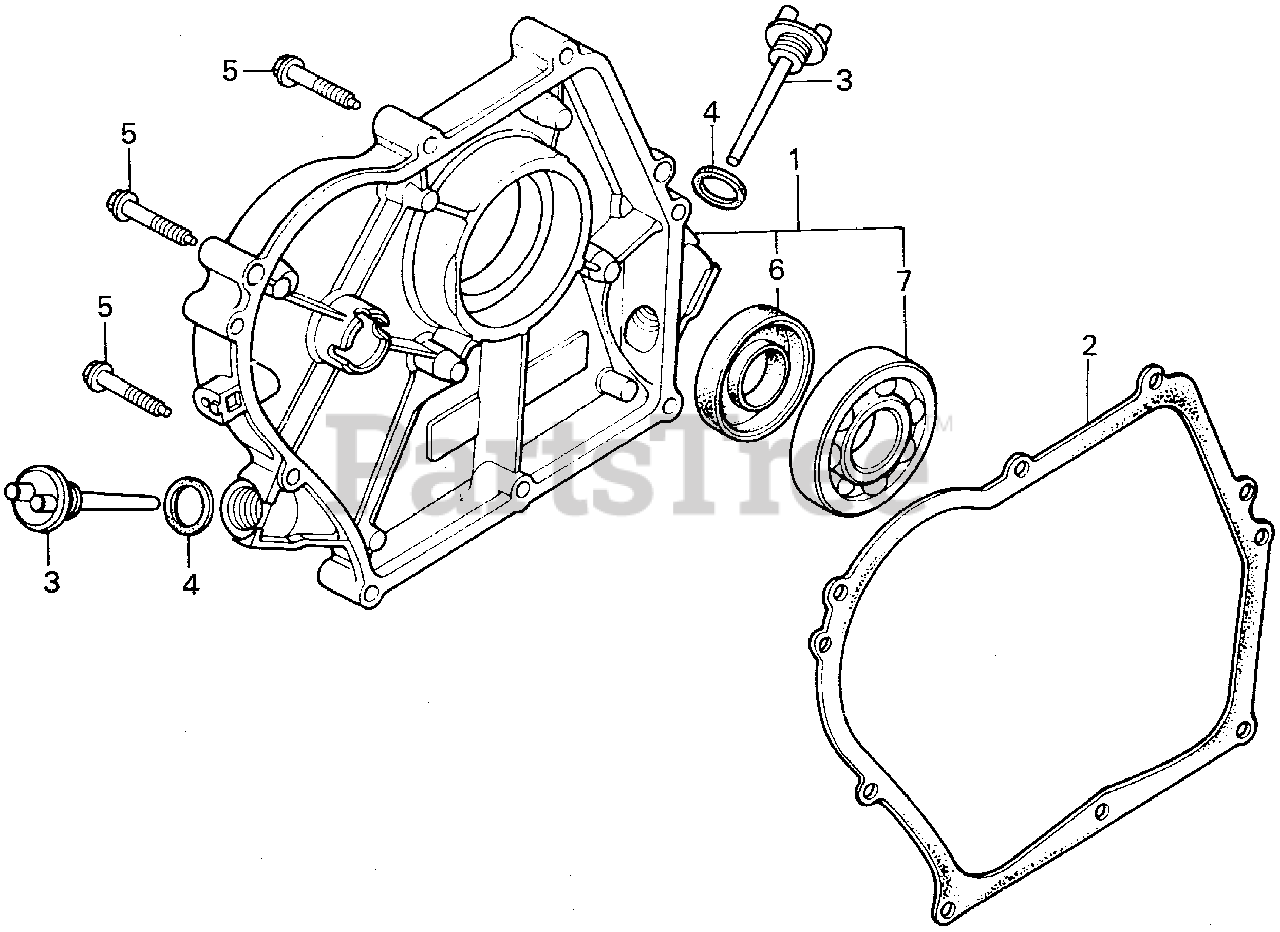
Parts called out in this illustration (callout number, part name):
1	COVER ASSY., CRANKCASE (Q-TYPE)
1	COVER ASSY., CRANKCASE (U-TYPE)
2	GASKET, COVER
4	GASKET, OIL FILLER CAP
5	BOLT, FLANGE (6X32)
6	OIL SEAL (25X41X6)
7	BEARING, RADIAL BALL (6205)
